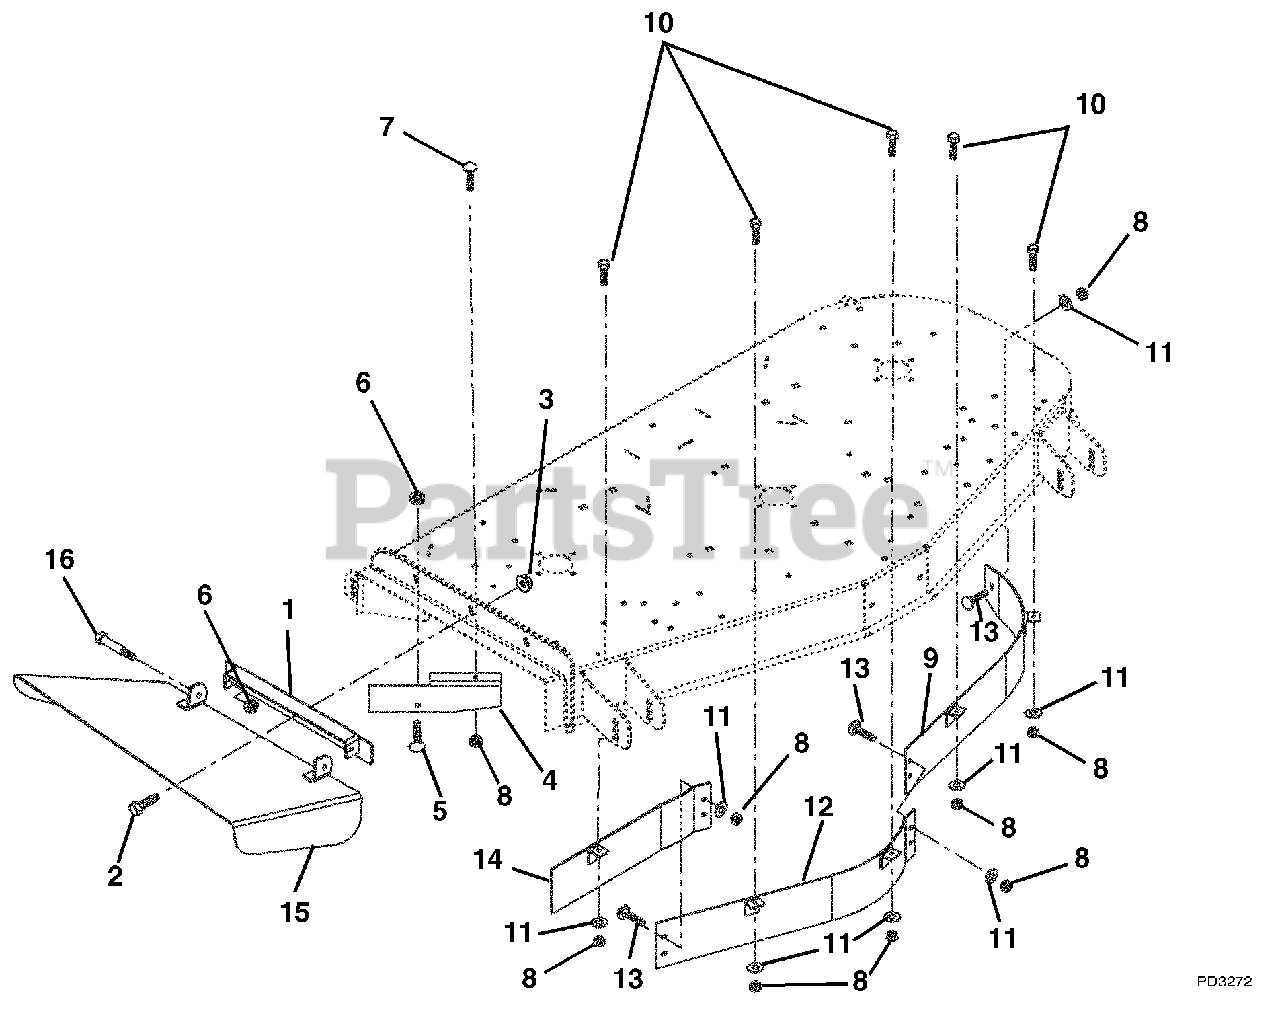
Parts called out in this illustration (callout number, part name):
1	Weldment, Discharge Chute Bracket
2	Bolt-Hex .38-16 x 1.00 Grade 5
3	Nut-Locking-Flange .38-16
4	Deflector, 72"
5	Bolt-Round Head Square Neck .38-16 x 1.00 Grade 2
6	Nut-Locking-Center .38-16
7	Bolt-Round Head Square Neck .31-18 x 1.00 Grade 5
8	Nut-Locking-Nylon .31-18
9	Weldment, 72" Left Hand Baffle
10	Bolt-Hex .31-18 x 1.00 Grade 5
11	Washer-Flat-Steel .312 x .734 x .065
12	Weldment, 72" Center Baffle
13	Bolt-Round Head Square Neck .31-18 x .75 Grade 2
14	Weldment, 72" Right Hand Baffle
15	Weldment, Discharge Chute 72"
16	Bolt-Shoulder .38-16 x .38
17	72" S.D. Mulch Kit
18	72" Discharge Cover Kit
